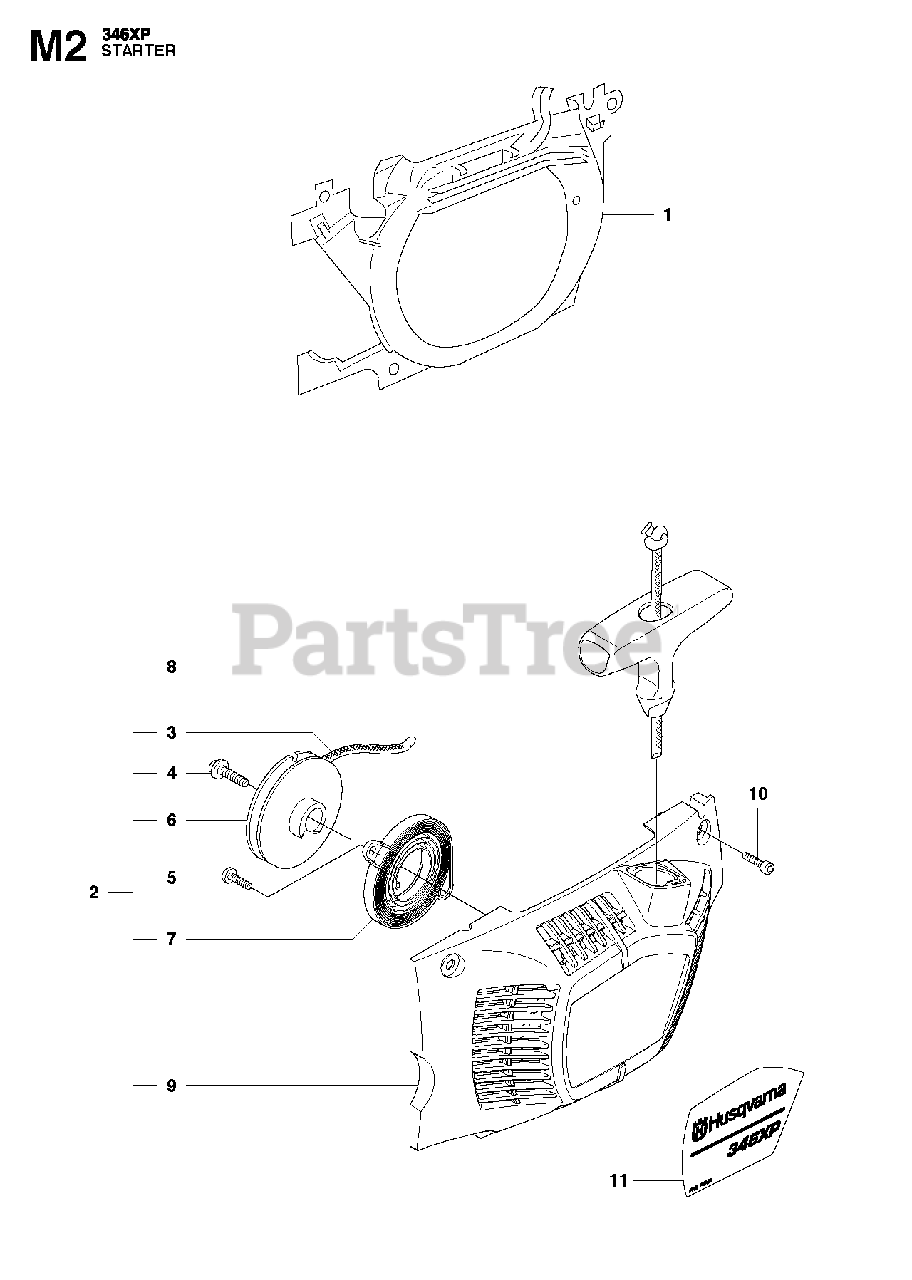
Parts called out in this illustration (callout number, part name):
1	AIR CONDUCTOR
3	STARTER ROPE
4	SCREW
5	SCREW
6	PULLEY
7	RETURN SPRING
8	HANDLE
9	STARTER HOUSING
11	LABEL
11	Label
